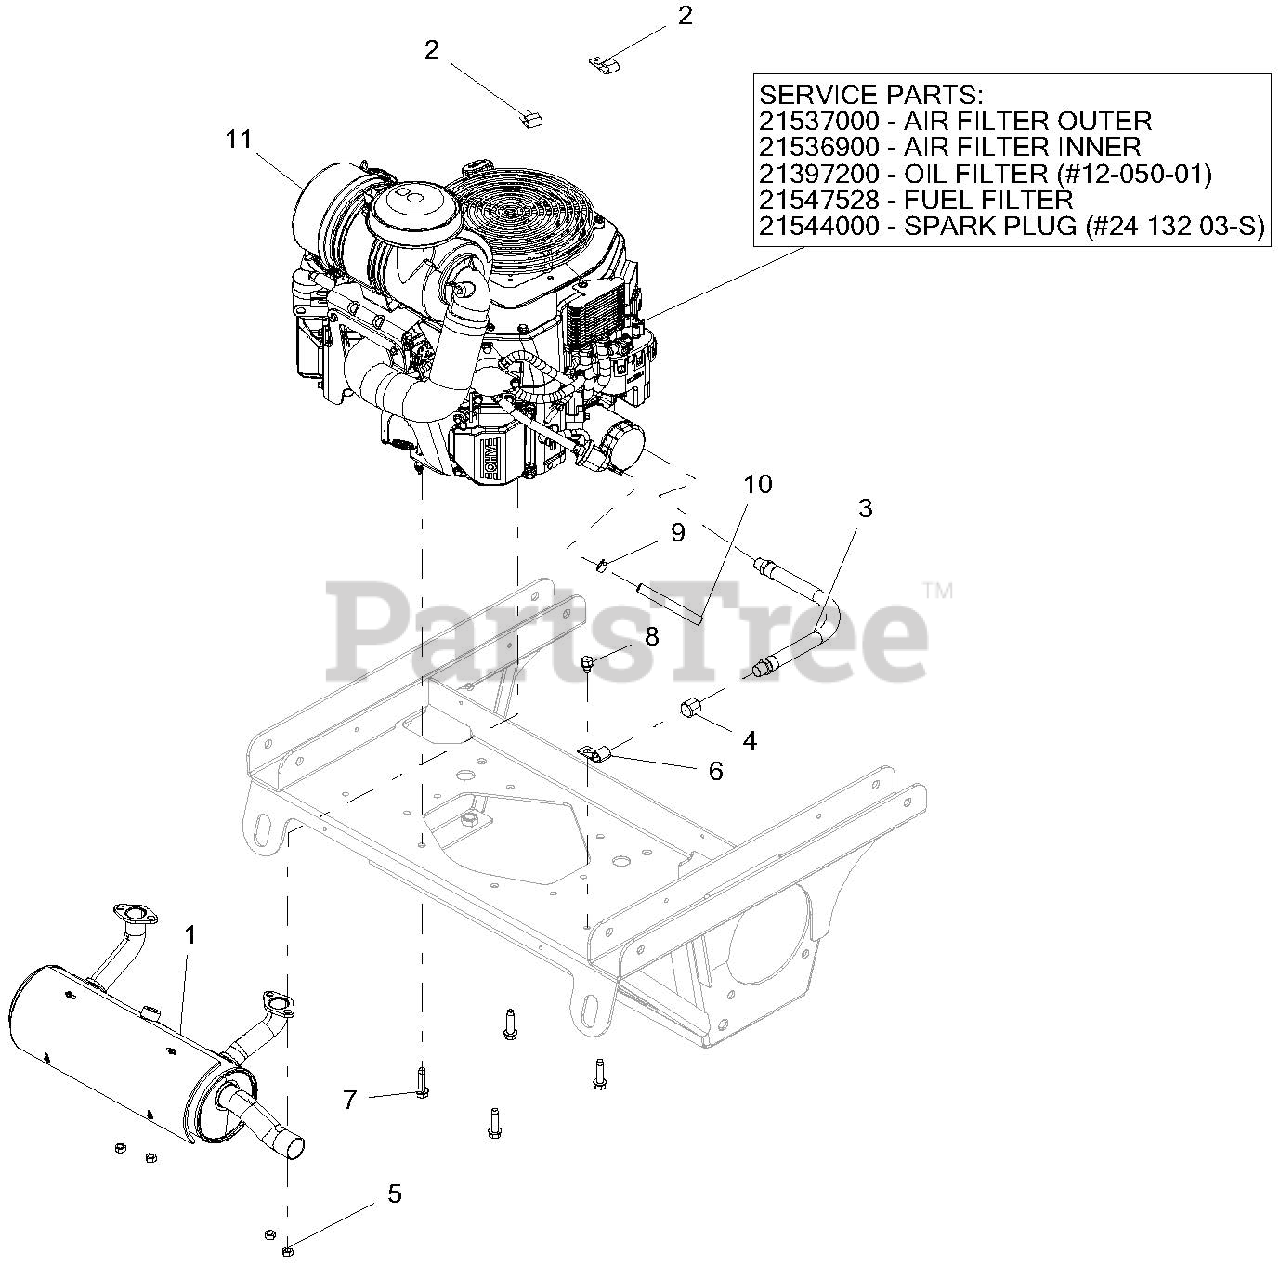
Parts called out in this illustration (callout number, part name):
1	MUFFLER, KOHLER EFI
2	CLAMP, J
3	HOSE, HYD .38-11-OK M6N0-M6N0
4	PIPE, CAP 3/8 NPT FEMALE
5	NUT-LK-TOP M8-1.25 YWZC
7	SCR-TAP .38-16X1.50 HWH TR YZ
8	SCR-TAP .38-16X.50 HWH TR YWZ
9	CLAMP, FUEL LINE
10	.25 LOW-PERM GAS HOSE 47.00" LG
11	ENGINE, KOHLER EFI ECV749
11	AIR FILTER OUTER
11	AIR FILTER INNER
11	OIL FILTER (#12-050-01)
11	FUEL FILTER
11	SPARK PLUG (#24 132 03-S)
